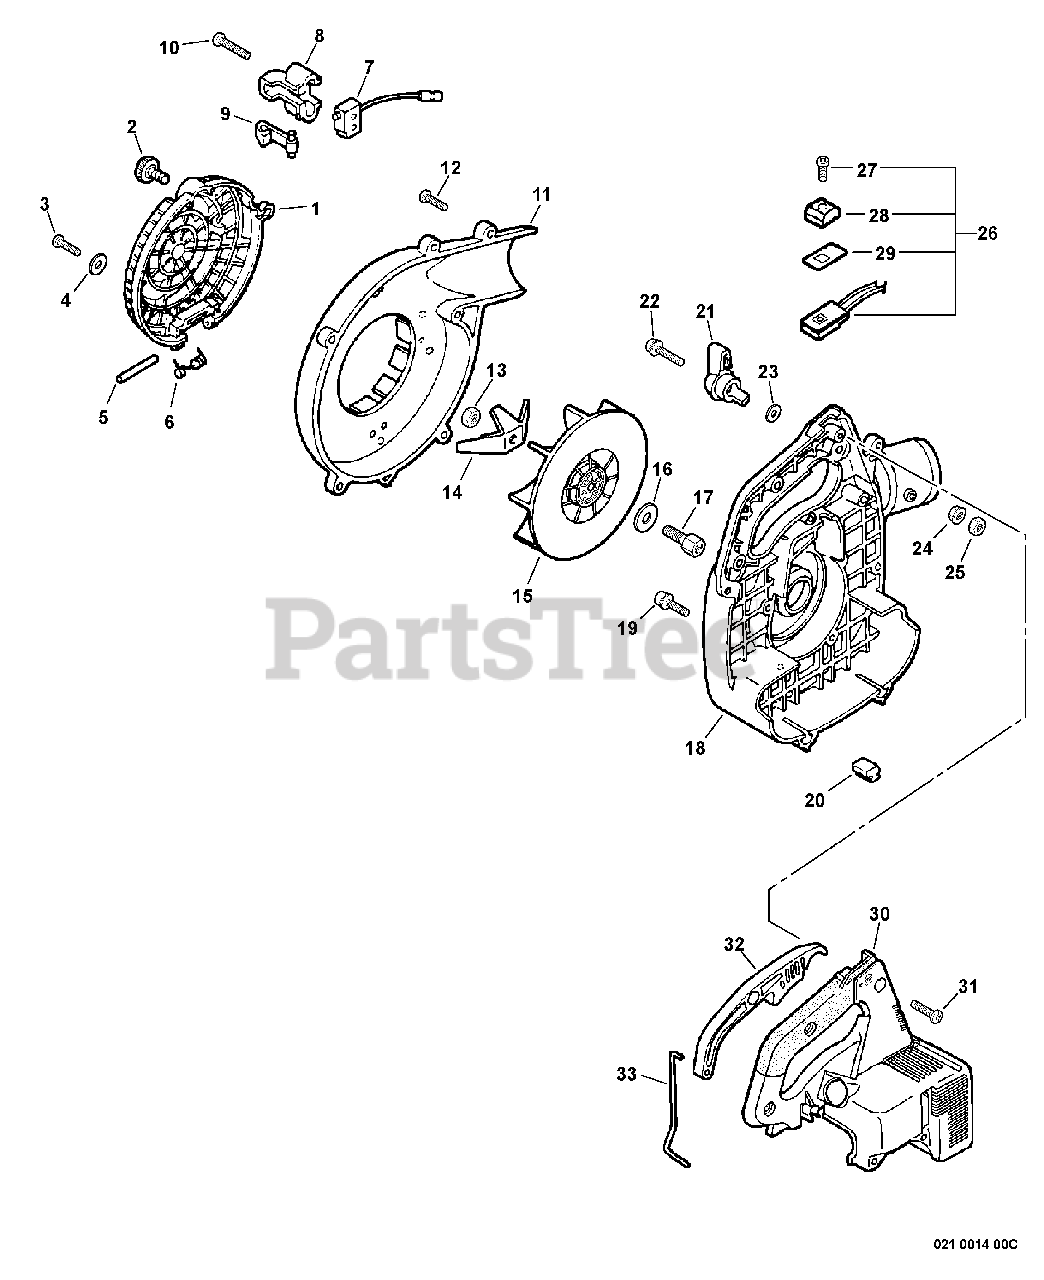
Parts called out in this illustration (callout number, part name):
1	COVER, INTAKE
2	THUMBSCREW
3	SCREW 5×14
4	WASHER 5.5×12×0.8
5	PIN, INTAKE COVER
6	SPRING, COIL
7	SWITCH, INTERLOCK
8	BRACKET, SWITCH
9	LEVER, SHUT OFF ACTUATOR
10	SCREW 4×22
11	COVER, FAN - LEFT -- ORANGE
12	SCREW, TAPPING 5×20
14	SHREDDER
17	HUB, FAN
18	COVER, FAN - RIGHT -- ORANGE
19	SCREW 4×22
21	CONTROL, THROTTLE
22	SCREW 5×25
23	WASHER 5.5×12×0.8
24	NUT, FLANGE M5
26	CABLE ASSY, CONTROL
27	SCREW 3×10
28	KNOB, SWITCH - ORANGE
29	LABEL, SWITCH
30	COVER, ENGINE
31	SCREW, TAPPING 5×20
32	CONTROL, THROTTLE
33	ROD, THROTTLE
